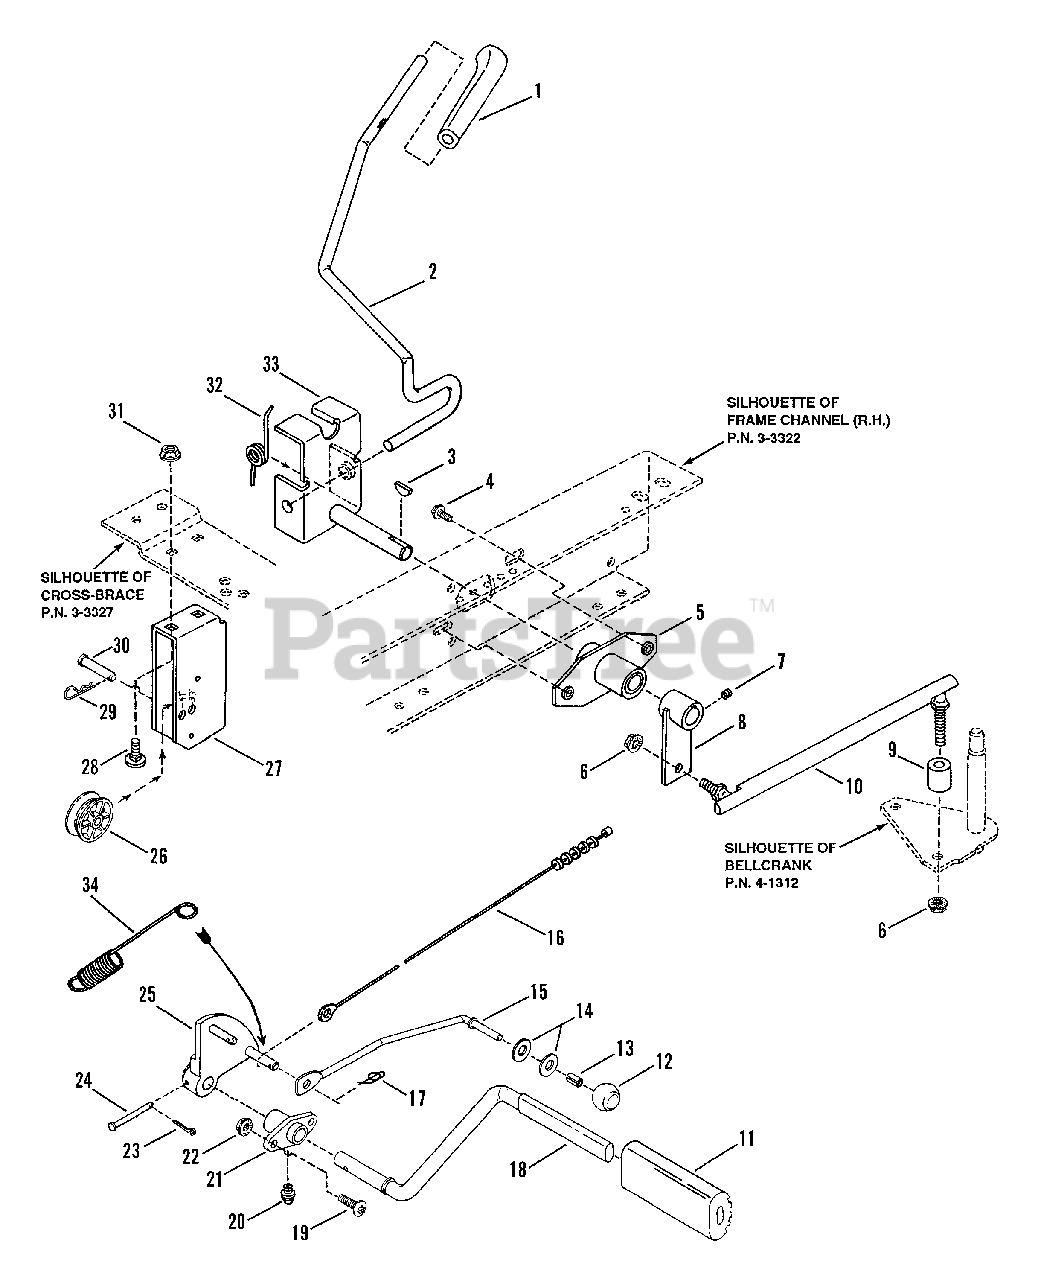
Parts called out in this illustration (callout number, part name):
1	KNOB, Shifter
2	SHIFTER, Transmission
3	KEY, Woodruff (No. 9)
4	SCREW, 5/16-18 x 5/8" H.W. Self-Tapping
5	SHIFT PIVOT ASSM'Y.
6	NUT, 5/16-24 Hex Flange Lock
7	SETSCREW, 5/16-18 x 5/16"
8	LEVER, Shift
9	SPACER, Shift Link
10	SHIFT LINK, Bellcrank
11	PAD, Pedal
12	KNOB, Latch
13	RING, Tolerance 5/16" x 1/2
14	WASHER, Nylon 5/16"
15	LATCH, Clutch/Brake
16	CABLE, Brake
17	COTTER-PIN, 3/8 Self-Lock
18	PEDAL, Clutch/Brake
19	SCREW, 5/16-18 x 7/8" Torx
20	FITTING, Lube 5/16"
21	PIVOT, Clutch/Brake Pedal
22	NUT, 5/16-18 Hex Lock
23	COTTER-PIN, 3/32 x 1"
24	PIN, Clevis, 3/16 x 1 1/2"
25	BRAKE ARM
26	SPOOL, Bracket
27	BRACKET, Spool
28	BOLT, 1/4-20 x 5/8" Flat Head Short Neck Carriage
29	PIN, Hair 1.12"
30	PIN, Clevis, 3/8 x 1 9/32"
31	NUT, 1/4-20 Hex Flange Lock
32	SPRING, Shifter
33	CHANNEL, Shifter
34	SPRING, Clutch
33322	FRAME CHANNEL
33327	CROSS-BRACE
41312	BELL CRANK
